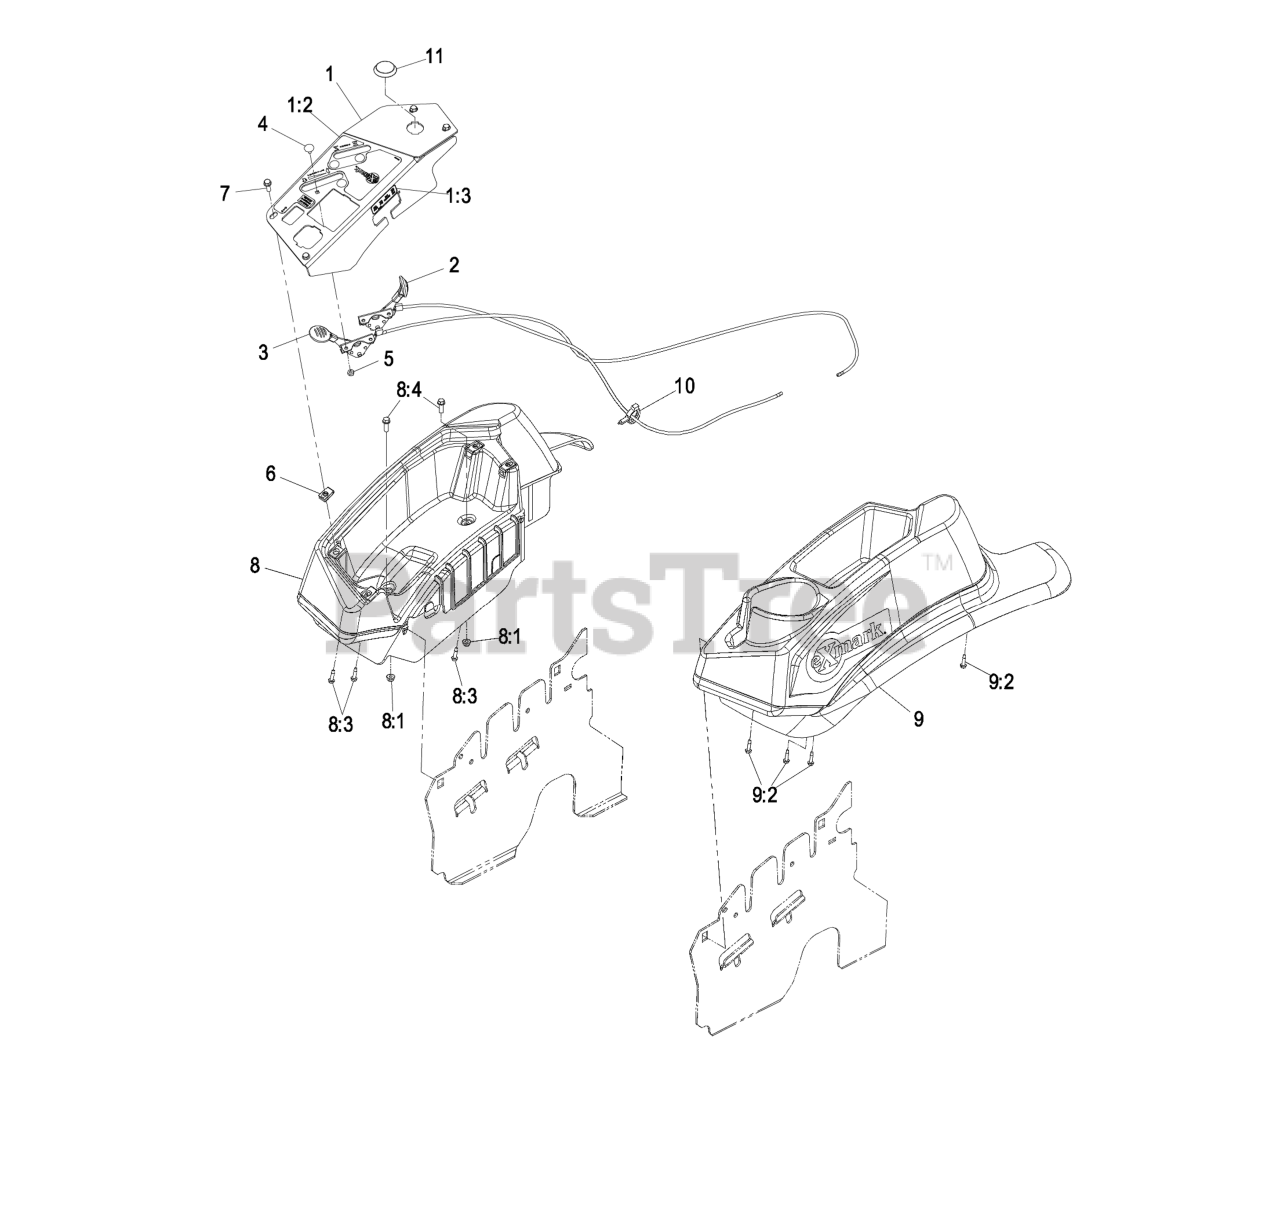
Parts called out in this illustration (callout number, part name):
1	CONSOLE,PANEL W/DECAL
1:2	DECAL-CONTROL PANEL
1:3	DECAL-FUSE
2	ASM,CHOKE CABLE
4	BOLT-CARR
5	NUT-LOCK, NI
7	SCREW-HWH
8	CONSOLE,RH NARROW ASM
8:3	SCREW,THD FORM,HWH
8:4	SCREW-HWH
9	CONSOLE.LH NARROW ASM
9:2	SCREW,THD FORM,HWH
10	CLAMP-HOSE
